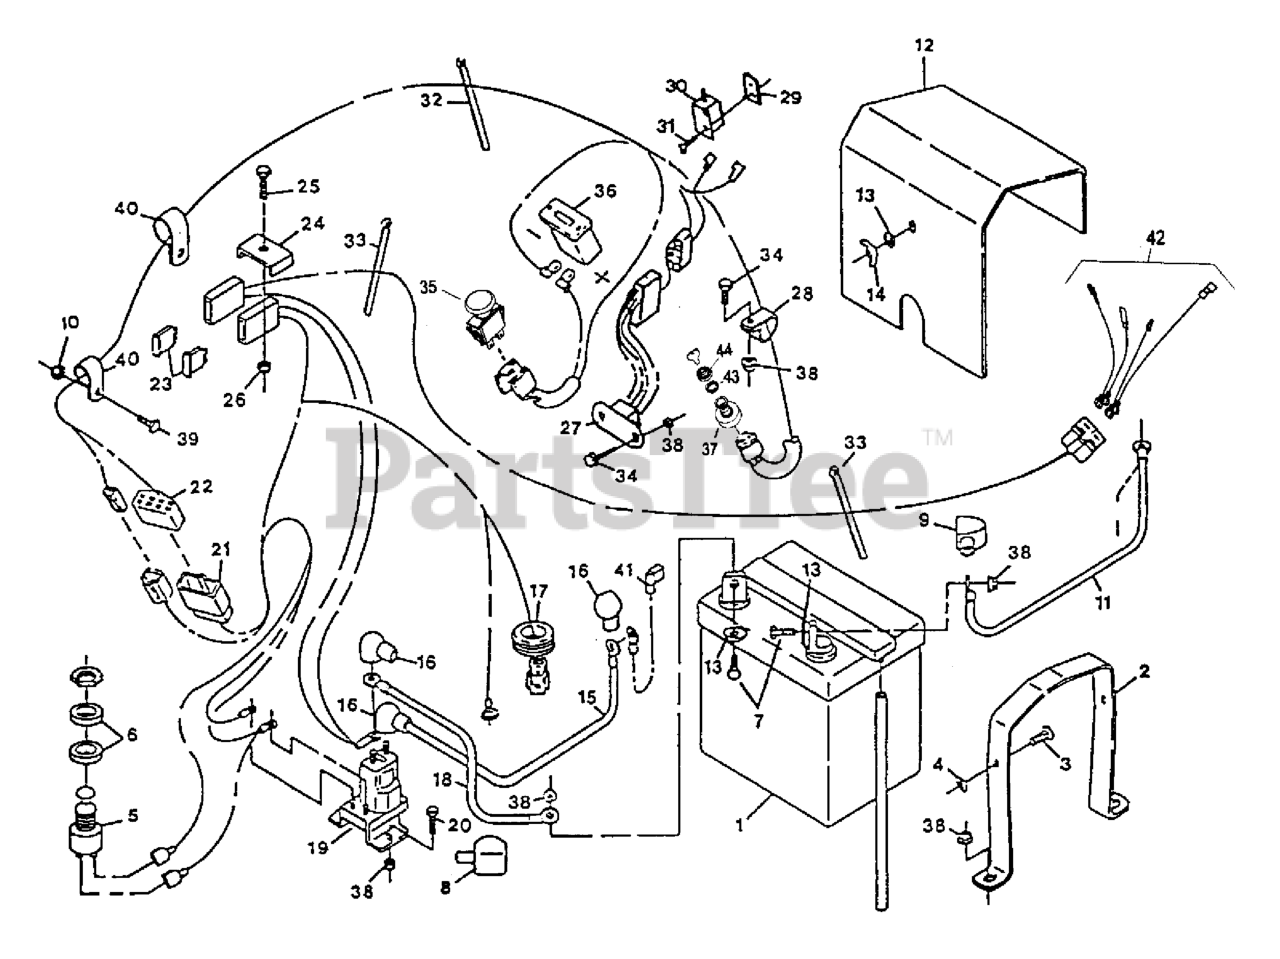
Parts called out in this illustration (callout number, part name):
2	Strap, Battery Holddown
3	BOLT-CARR
4	NUT-RETAINING
5	SWITCH,PUSH BUTTON
7	SCREW-HH
9	INSULATOR, BATTERY -
10	NUT-HHF, WHIZ
11	WIRE-GROUND
13	WASHER-FLAT
14	NUT-WING
16	INSULATOR-SOLENOID
17	GROMMET
20	SCREW-HH
21	HARNESS,WIRING HYDRO
22	HARNESS,CONSOLE-TT
23	FUSE-BLADE TYPE, 20 AMP
24	CLIP-FUSE BLOCK PLTD
25	SCREW-HH
26	NUT-LOCK, NI
27	MODULE-OPC NO TIME DELAY
28	CLIP-LOOM
29	PLATE-TAPPED
30	SWITCH-OPEN, NORMALLY
31	SCREW-PPH
32	TIE-PLASTIC
33	TIE-CABLE
34	SCREW-HH
36	METER-HOUR
37	SWITCH,IGNITION
38	Nut, Whizlock 1/4-20
39	SCREW-HH
40	CLIP-LOOM
42	HARNESS,WIRING 19KA
43	NUT-SWITCH, IGNITION
44	SEAL-SWITCH, IGNITION
